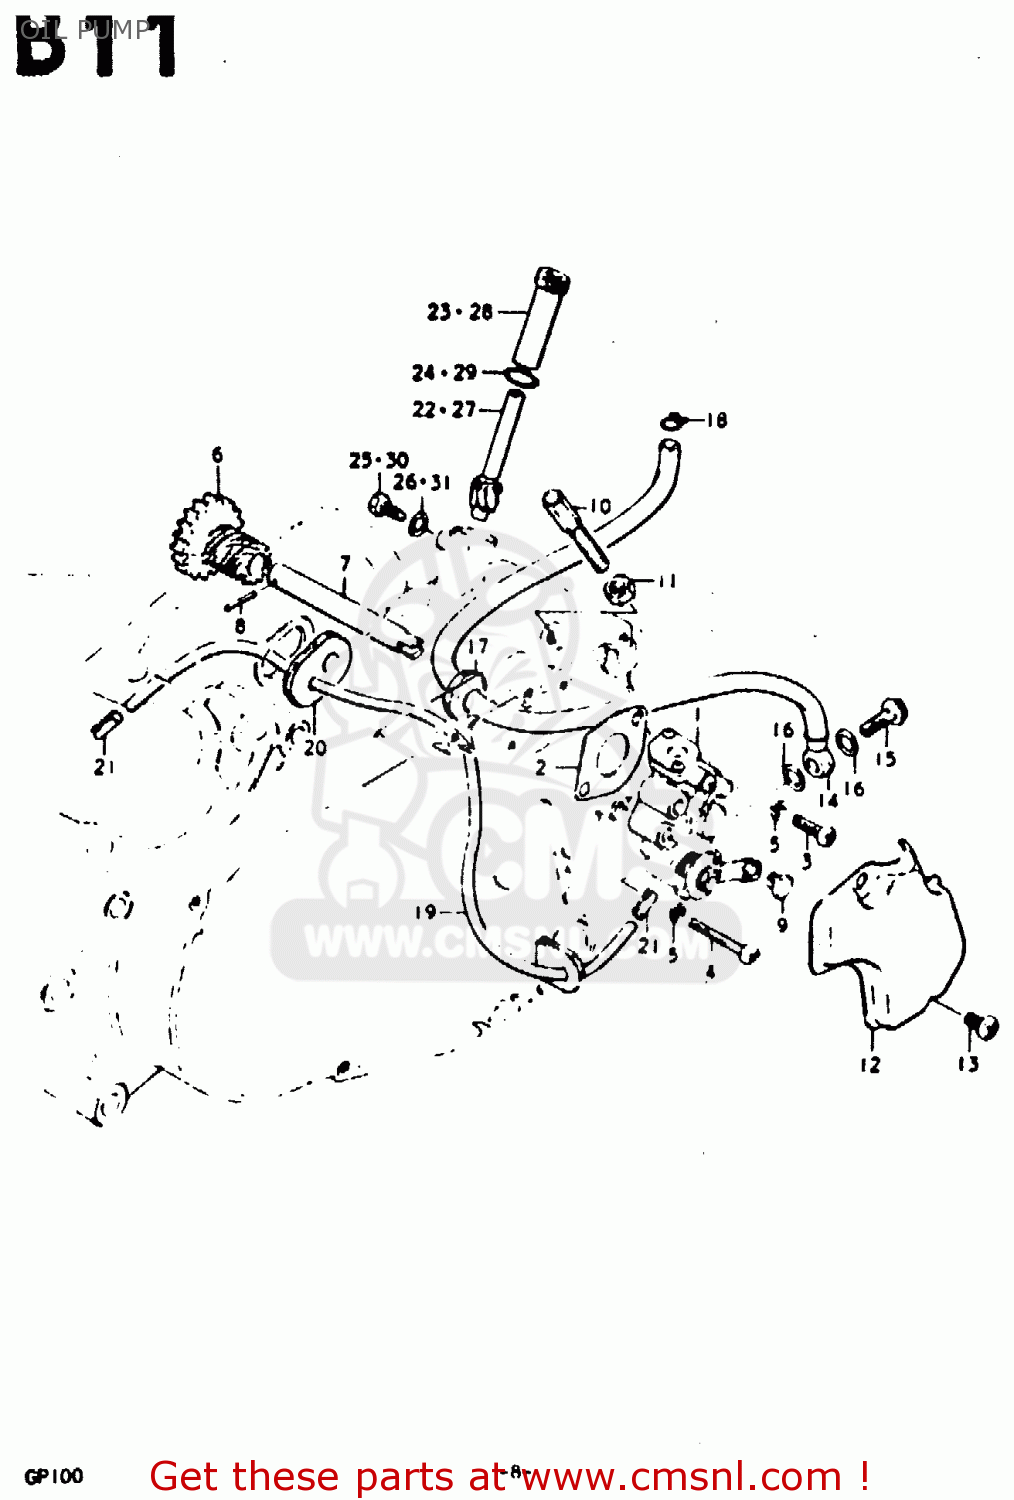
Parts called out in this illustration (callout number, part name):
1	PUMP ASSY, OIL
2	GASKET,OIL PUMP (MCA)
3	SCREW
4	SCREW
5	LOCK WASHER
6	GEAR,OIL PUMP DRIVE
7	SHAFT,OIL PUMP DRIVE GEAR
8	PIN(2.5X19.8)
9	TERMINAL,CABLE
10	BOLT
11	NUT
12	CAP,OIL PUMP INSPECTION
13	SCREW
14	HOSE,OIL NO.1
15	UNION BOLT
16	GASKET(6.2X11X1).2 (NAS)
17	GROMMET
18	CLIP
19	HOSE,OIL NO.2
20	GROMMET,OIL HOSE NO.3
21	CLIP
